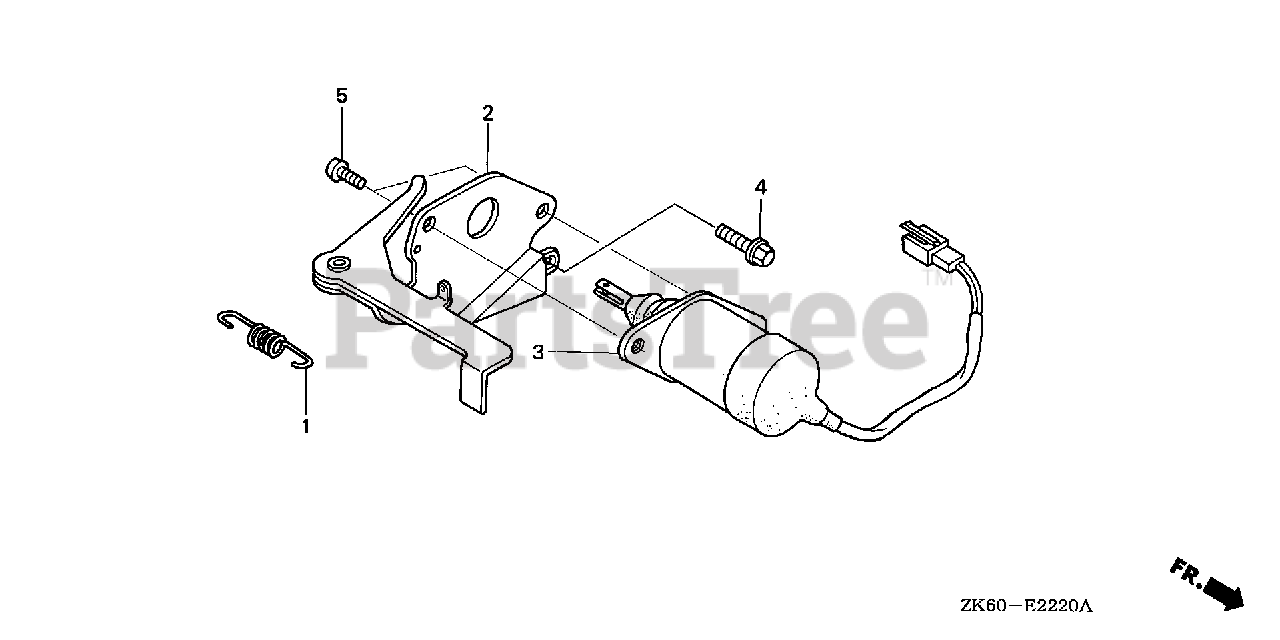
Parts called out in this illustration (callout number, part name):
1	SPRING, CHOKE RETURN
2	LEVER, THROTTLE
3	SOLENOID ASSY.
4	BOLT, FLANGE (6X12) (CT200)
5	SCREW, PAN (5X8)
